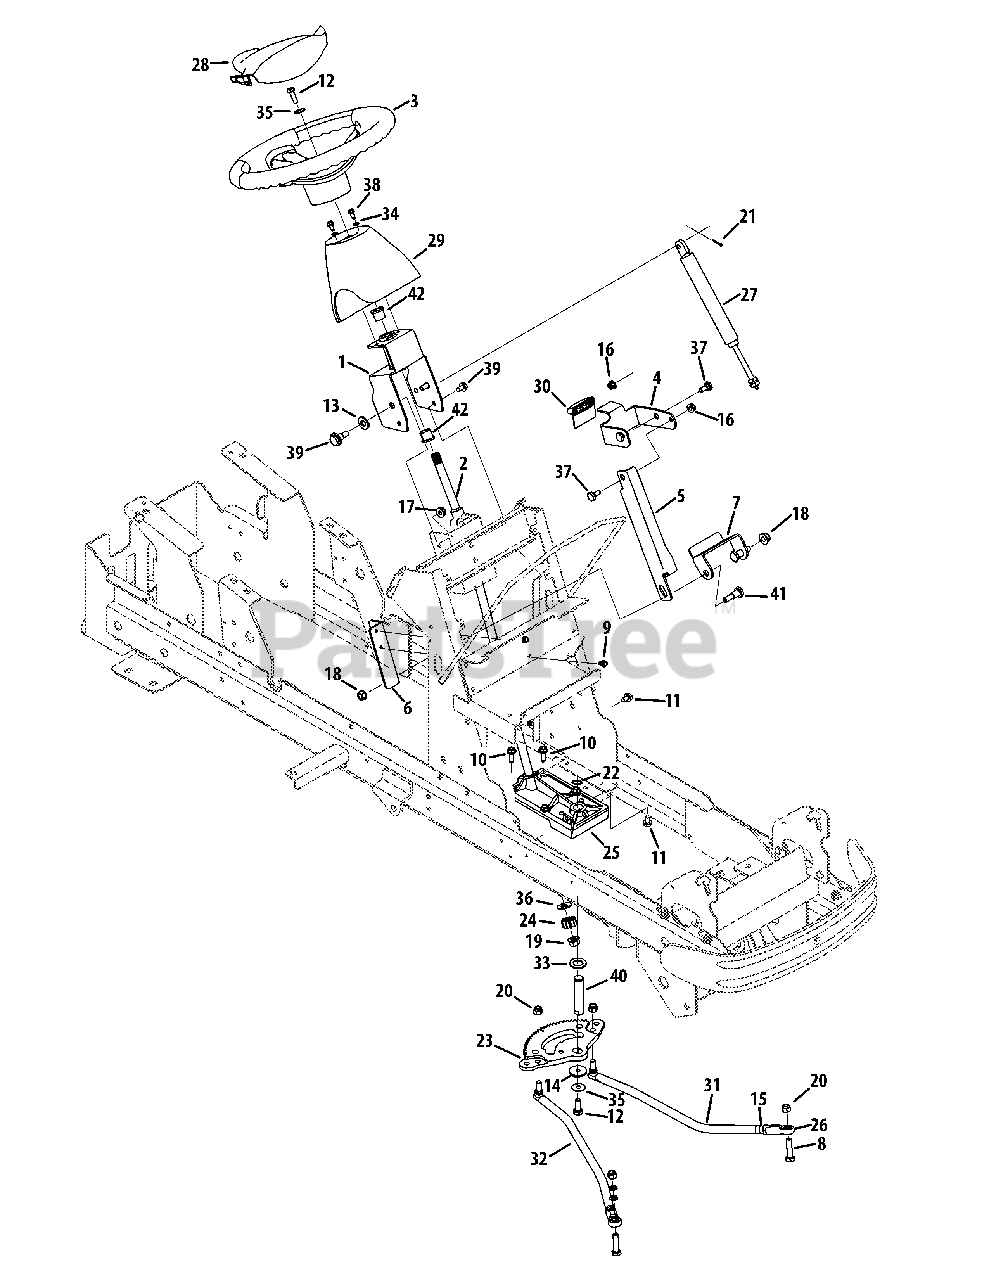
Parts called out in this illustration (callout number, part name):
2	Manual Steering Assembly
3	Steering Wheel
4	Tilt Steering Lever Bracket
5	Tilt Steering Bracket
6	Tilt Steering Mount Bracket
7	Tilt Steering Pivot Bracket
8	Hex Screw, 3/8-24 x 2.00
9	Hex Washer Screw, 1/4-20 x .500
10	Hex Washer Screw, 5/16-18 x 1.000
11	Hex Washer Screw, 5/16-18 x .625
12	Hex Lock Screw, 5/16-18 x 1.00
13	Flat Washer, .510 x 1.00 x .125
14	Flat Washer, .340 x 1.50 x .150
15	Jam Nut, 7/16-20
16	Flange Lock Nut, 5/16-18
17	Flange Lock Nut, 3/8-16
18	Flange Lock Nut, 3/8-16
19	Flange Lock Nut, 7/16-20
20	Hex Lock Nut, 3/8-24
21	Cotter Pin, 3/32 x .750
22	Snap Ring, .750
23	Segment Gear
24	Pinion Gear
25	Steering Housing
26	End Rod, 7/16-20 x 3/8
27	Locking Damper Cylinder
28	Steering Wheel Cover
29	Dash Collar
30	Tilt Lever
31	LH Drag Link, 5/8
32	RH Drag Link, 5/8
33	Flat Washer, .76 x 1.25 x .10
34	Flat Washer, .344 x .62 x .033
35	Bell Washer, .340 x .872 x .060
36	Thrust Washer, .510 x 1.12 x .060
37	Shoulder Screw, .435 x .178-5/16 x .56
38	Shoulder Screw, 1/4-20 x 0.500
39	Shoulder Bolt, 3/8-16 x .49 x .33
40	Steering Shaft
41	Shoulder Screw, 3/8-16 x .50 x .66
42	Flange Bearing, .630
